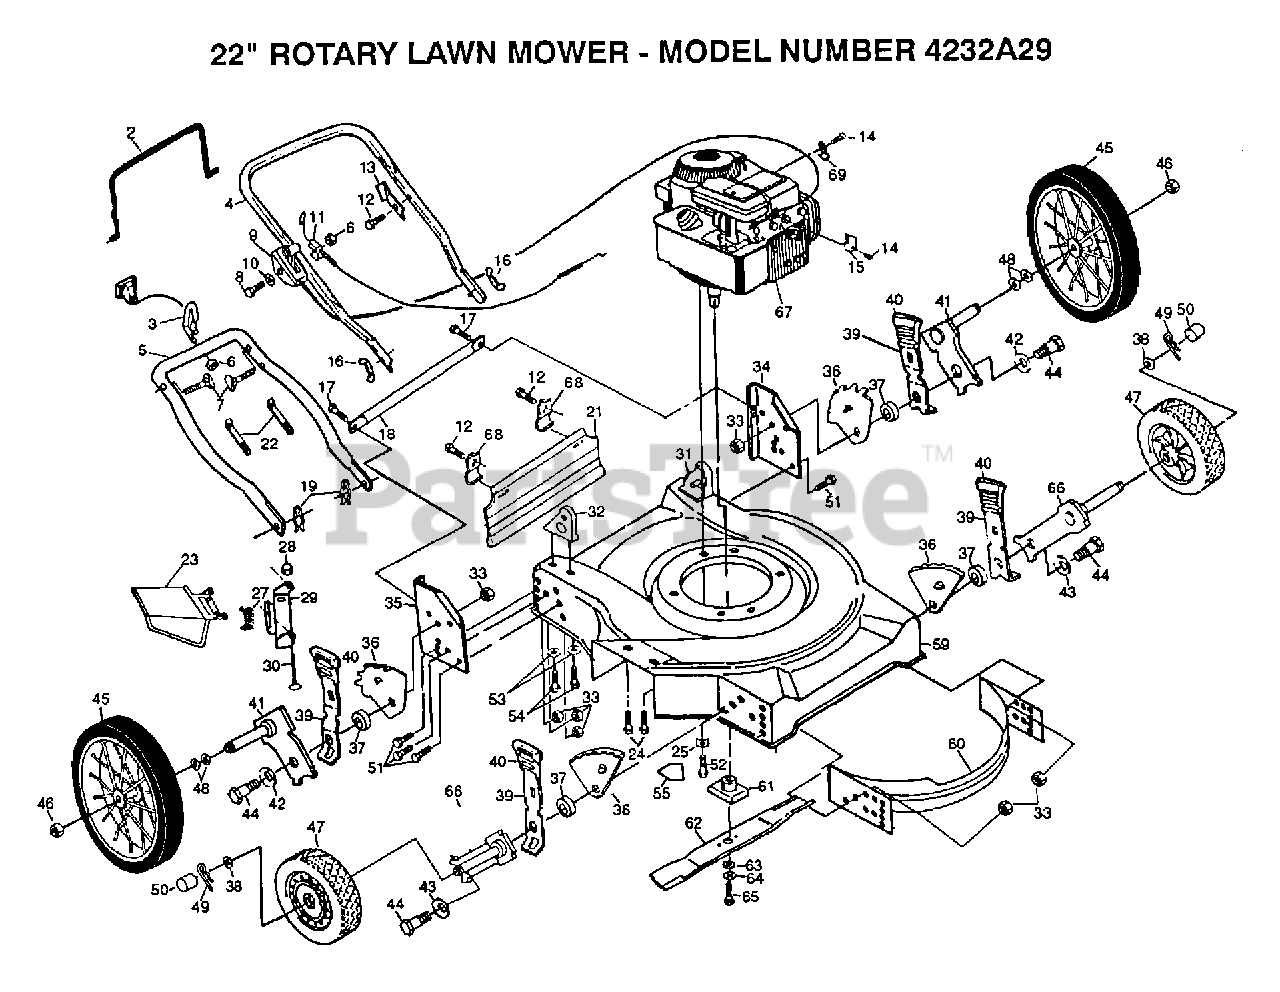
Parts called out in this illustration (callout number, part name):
2	CONTROL BAR PM
3	ROPER GUIDE PM
7	BOLT.HANDLE.LM
8	SCREW
9	CONTROL THROTTLE
10	WASHER PM
11	CABLE.ASM
12	TAPPING SCREW
13	"BRKT,UPSTOP"
14	SCREW PM
15	CABLE CLAMP
16	"NUT,WING PM"
17	SCREW
18	ROD.SUPPORT.WB.
19	HAIRPIN COTTER
24	SCREW
27	"SPRING,TORSION"
28	PUSH ON SPEED NUT
29	"BRKT,HSG"
30	"ROD,HINGE "
33	LOCKNUT PM
38	WASHER
40	KNOB PM
41	AXLE ARM ASSY R
43	"WASHER, BELLEVIL."
45	WHEEL & TIRE PM
46	HEX FLANGE LOCKNT
47	WHEEL.ASM
48	WAVE WASHER
49	RETAINER CLIP PM
50	HUB CAP-PLASTIC
52	SCREW
53	STEEL WASHER
54	SCREW
55	DECAL-DANGER PM
61	BLADE ADAPTOR
62	"BLADE.22"""
63	"WASHER,HARDEN"
64	LOCKWASHER
65	SCREW
66	AXLE ARM
68	"BRKT,DEFL PM"
69	"CLIP,CABLE"
